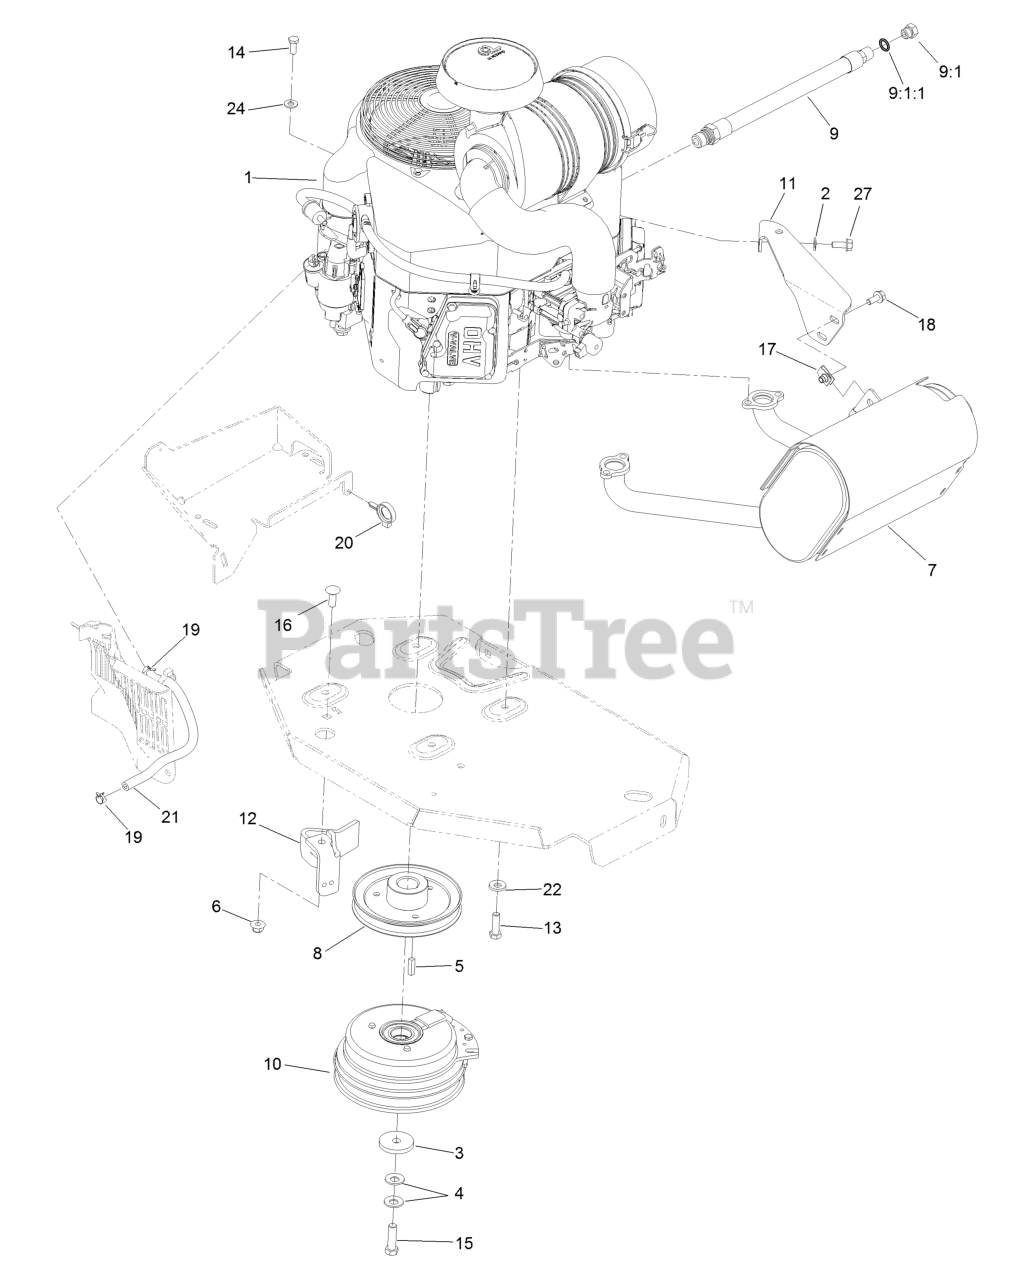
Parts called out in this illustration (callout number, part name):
2	WASHER-SPRING
3	WASHER-CLUTCH
4	WASHER-SPRING
6	NUT-HF, NI
7	MUFFLER
8	SHEAVE
9	ENGINE OIL DRAIN HOSE ASM
9:1	PLUG-HH
9:1:1	O-RING
10	CLUTCH KIT
11	BRACKET-MUFFLER
12	CLUTCH-ANCHOR
13	SCREW-HH
14	SCREW-HH
15	SCREW-HH 7/16-20 X 1 1/2 W/LOCTITE
16	SCREW-CARR
18	SCREW-HHF
19	CLAMP-HOSE
20	CLAMP-HOSE
21	HOSE-FUEL
22	WASHER-BELLEVILLE
24	WASHER-PLAIN
27	SCREW-HHF
